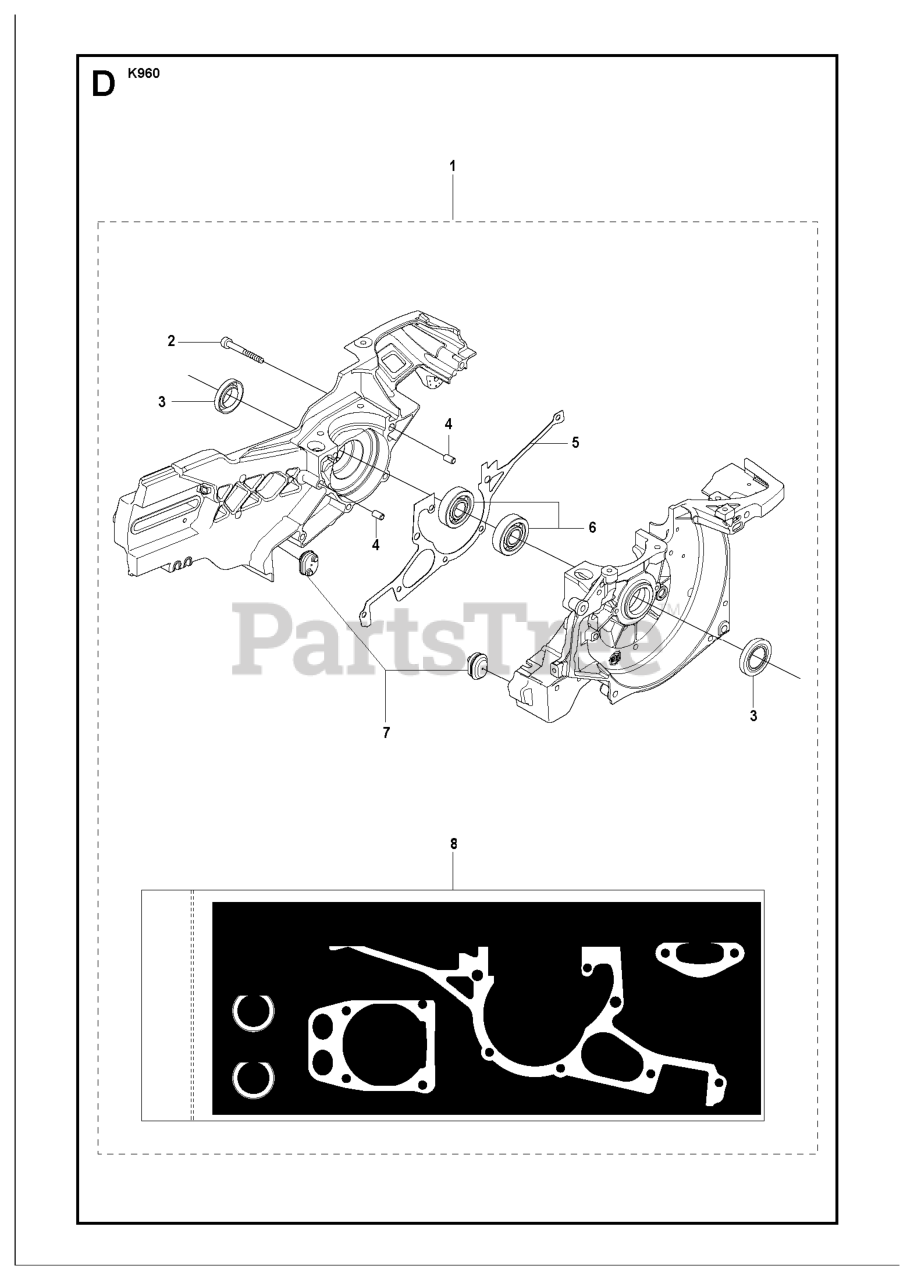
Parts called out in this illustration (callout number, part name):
1	%CRANKCASE ASSY
3	SEALING RING
5	RP GASKET
6	BALL BEARING 6203C3QE6
7	RUBBER BUSHING
8	RP GASKET KIT
9	RP GASKET
10	GASKET MUFFLER
